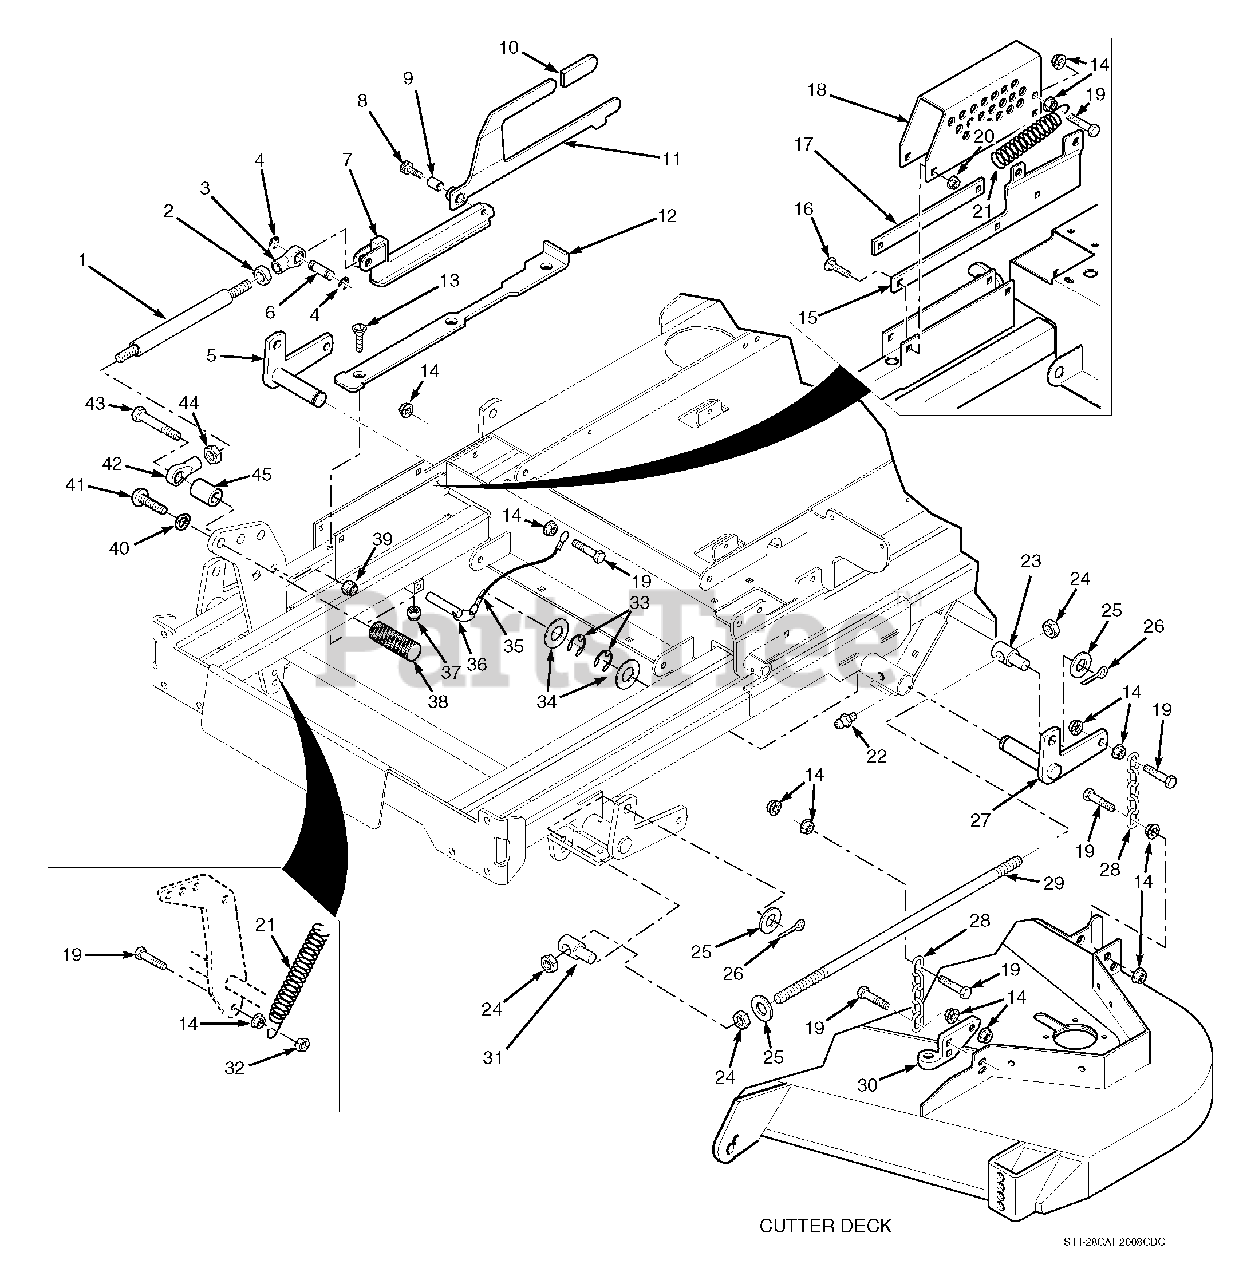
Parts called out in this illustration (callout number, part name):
1	Link, Deck Lift
2	Nut, Jam 1/2-20 LH
3	Rod End, Female - 1/2-20 LH
4	Ring, Retaining 1/2" External "E"
5	Bellcrank Weldment, RH Rear
6	Pin, Decklift
7	Slide Weldment, Height Adjustment
8	Bolt, Shoulder 1/2 x 3/4"
9	Bushing, .502 ID.
10	Grip, Deck Latch
11	Deck Latch
12	Lockplate, Decklift
13	Screw, Cap 5/16-18 x 3" FHHS
14	Nut, Hex Serrated Flange 3/8-16
15	Guide, Long
16	Bolt, Carriage 5/16-18 x 1"
17	Guide, Short
18	Bracket, Cutting Height Adjustment
19	Bolt, Hex Head 3/8-16 x 1-1/2"
20	Nut, Hex Serrated Flange 5/16-18
21	Spring, Helper
22	Grease Fitting
23	Swivel Joint, LH
24	Nut, Hex 5/8-11
25	Flatwasher, 5/8" (.656 x 1.312 x .095)
26	Cotter Pin, 3/16 x 1"
27	Bellcrank Weldment, LH Rear
28	Chain
29	Stud, 5/8-11 x 26.0"
30	Lever Assembly, Deck Level
31	Swivel Joint, RH
32	Locknut, 3/8-16 Center Lock
33	Ring, Retaining 1" External "E"
34	Flatwasher, 1" (1.062 x 1.50 x .048)
35	Lanyard, Deck Height Pin
36	Ring Pin, 1/2 x 3.06"
37	Nut, 3/8-16 Elastic Stop
38	Foot Pedal, Height Adjustment
39	Nut, Hex Elastic Stop 1/2-13
40	Lockwasher, 5/8"
41	Capscrew, 5/8-11 x 1-1/2"
42	Rod End, Female - 1/2-20 RH
43	Bolt, Hex Head 1/2-13 x 3"
44	Nut, Jam 1/2-20 RH
45	Spacer, Decklift Pedal
